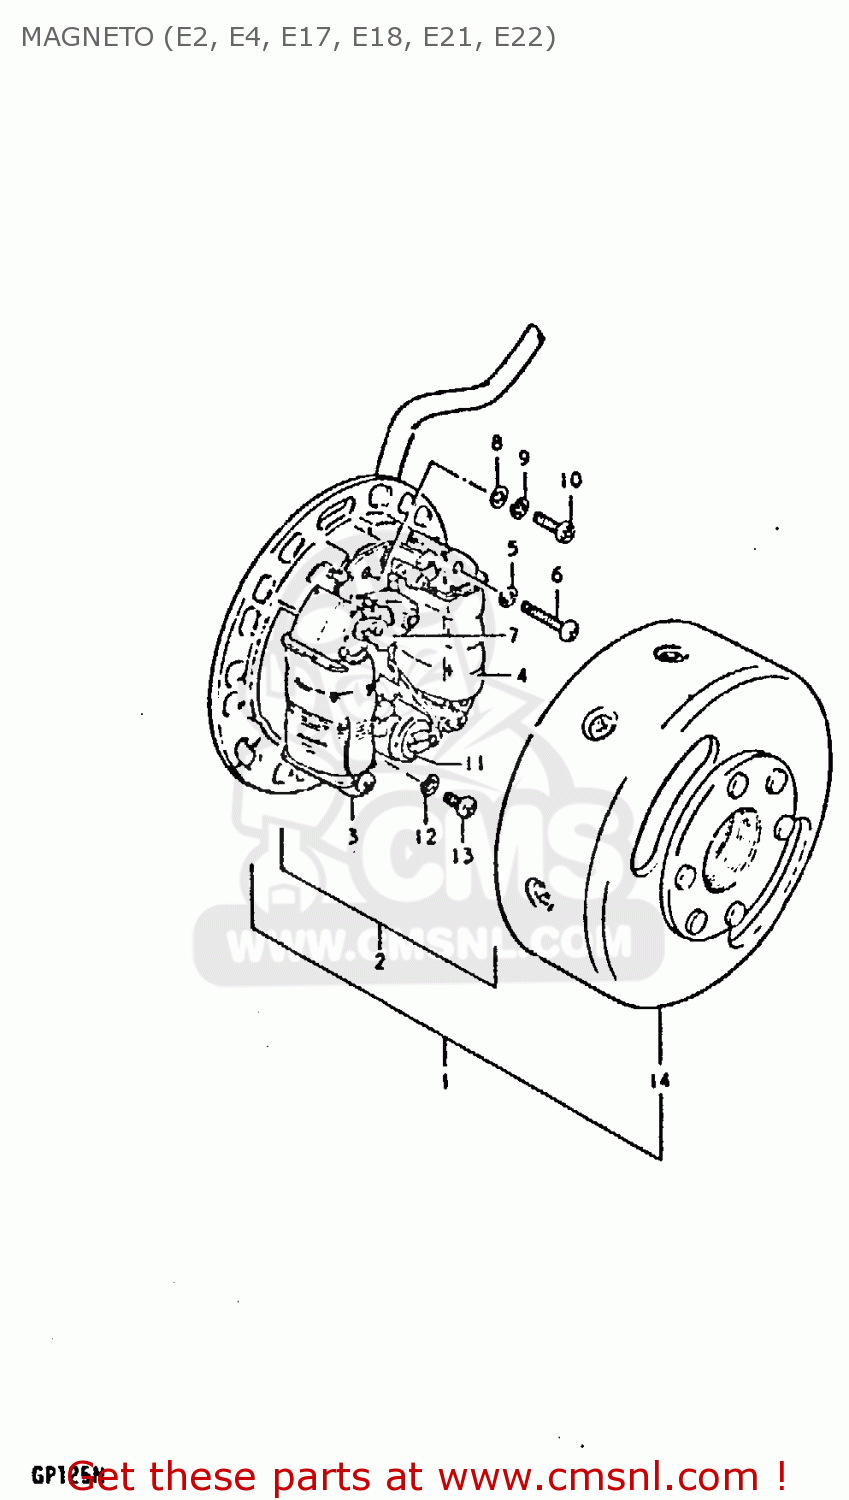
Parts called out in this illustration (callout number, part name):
1	MAGNETO ASSY
2	STATOR ASSY
3	COIL, LIGHTING
4	COIL,PRIMARY
5	LOCK WASHER
6	SCREW 4X25
7	POINT ASSY,CONTACT
8	WASHER
9	LOCK WASHER
10	SCREW(4X10)
11	CONDENSER
12	LOCK WASHER
13	SCREW 4X10
14	ROTOR, FRYWHEEL
